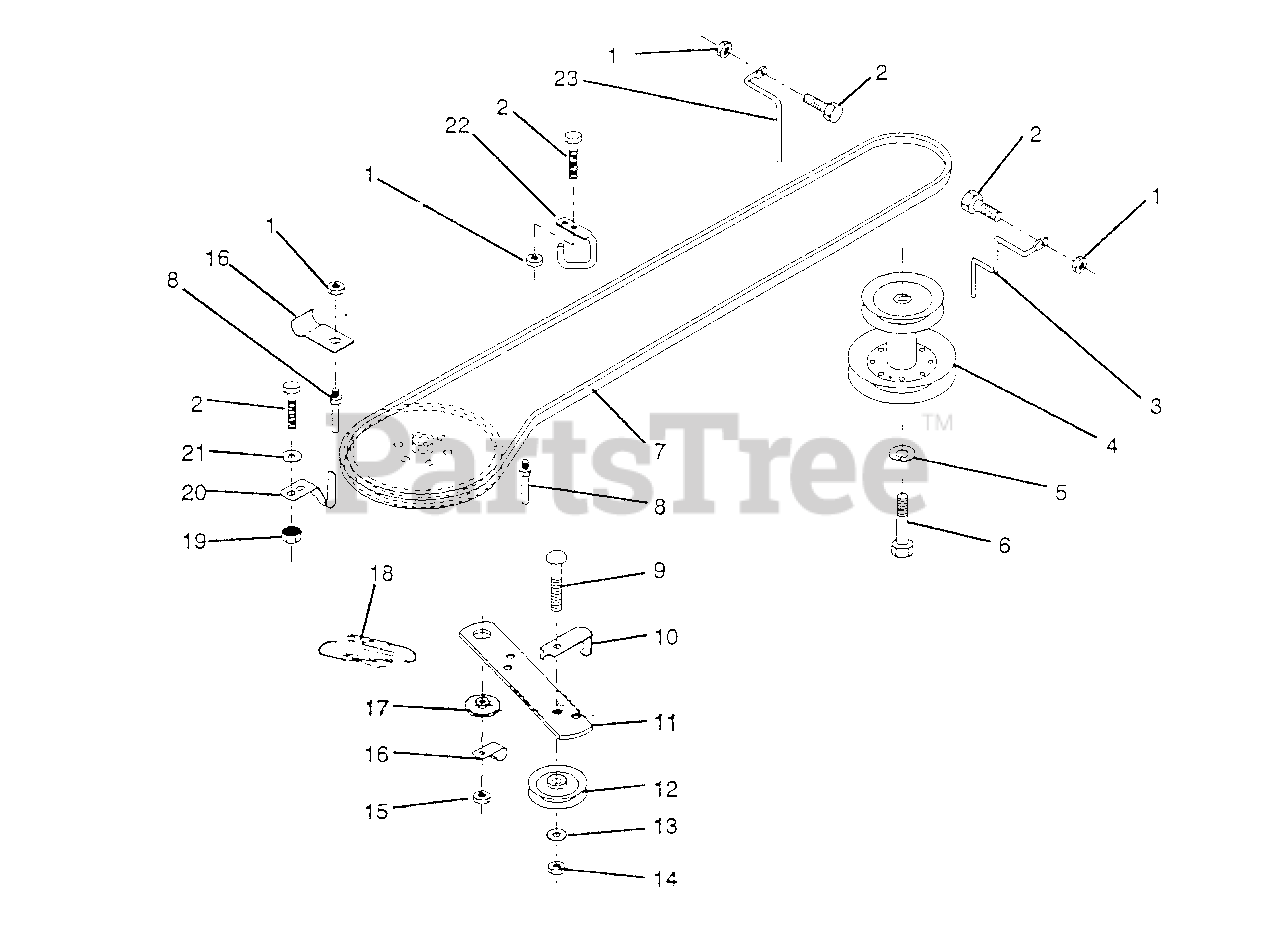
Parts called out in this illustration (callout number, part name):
1	Nut, Crownlock 5/16-18
2	Bolt, Hex Hd. 5/16-18 UNC x 3/4
3	Keeper, Engine Mower Drive R.H. Belt
4	Pulley, Engine
5	Washer, Lock Hvy. Helical Spring 7/16
6	Bolt, Fin. Hex 7/16-20 UNF x 1-1/4 Gr. 8
7	Traction, V-Belt Drive
8	Keeper, T/A Ground Drive Belt
9	Bolt, Carriage 3/8-16 UNC x 1-1/2
10	Keeper, Belt Ground Drive Idler
11	Arm, Ground Drive Clutch
12	Idler, Flat
13	Washer 13/32 x 13/16 x 16 Ga.
14	Nut, Centerlock 3/8-16 UNC
15	Nut, Crownlock 3/8-16 UNC
16	Clip, Insulated
17	Spacer, Retainer
18	Spring, Extension
19	Nut, Keps 5/16-18 UNC
20	Keeper, T/A Ground Drive Belt
21	Washer 11/32 x 5/8 x 16 Ga.
22	Keeper, Frame Ground Drive Belt
23	Keeper, Engine Mower Drive L.H. Belt
